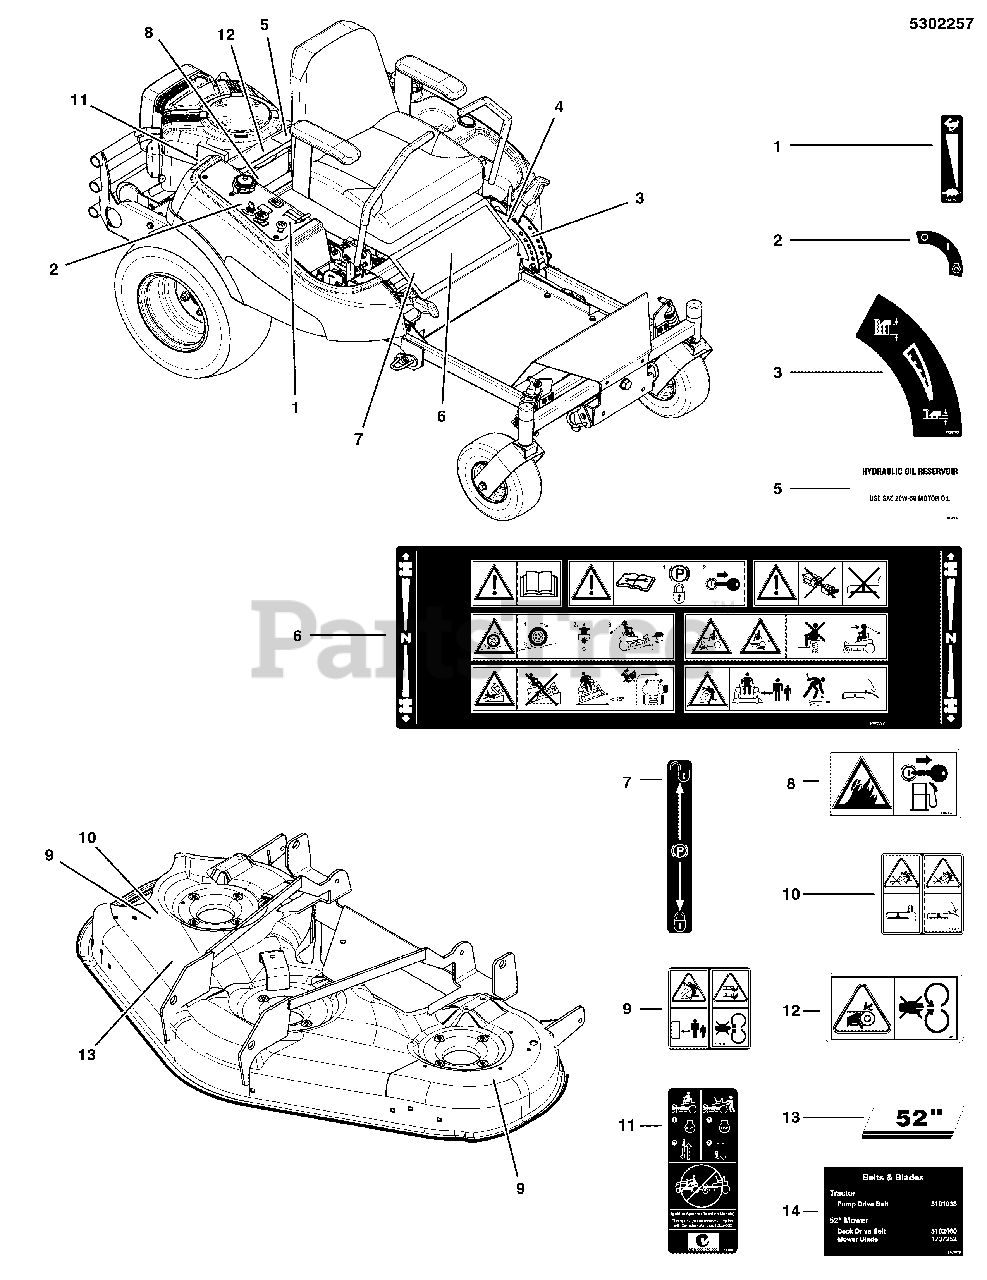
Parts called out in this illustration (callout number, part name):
1	DECAL, THROTTLE CONTROL
2	DECAL, IGNITION SWITCH
3	DECAL, HEIGHT OF CUT
4	DECAL, US PATENT, ZTR
5	DECAL, HYDRAULIC OIL, SAE 20W50
6	DECAL, MAIN SAFETY, ANSI CE
7	DECAL, PARKING BRAKE SYMBOLS
8	DECAL, FIRE ANSI EXPORT
9	DECAL, DANGER, MOWER DECK, ANSI EXP
10	DECAL, DANGER DISCHARGE ANSI EXPORT
11	DECAL, TRANSAXLE RELEASE
12	DECAL, CE DANGER
13	DECAL, 52"-SILVER ON BLACK W/STRIPE
14	DECAL, BELT & BLADE, ZT3000/355Z
